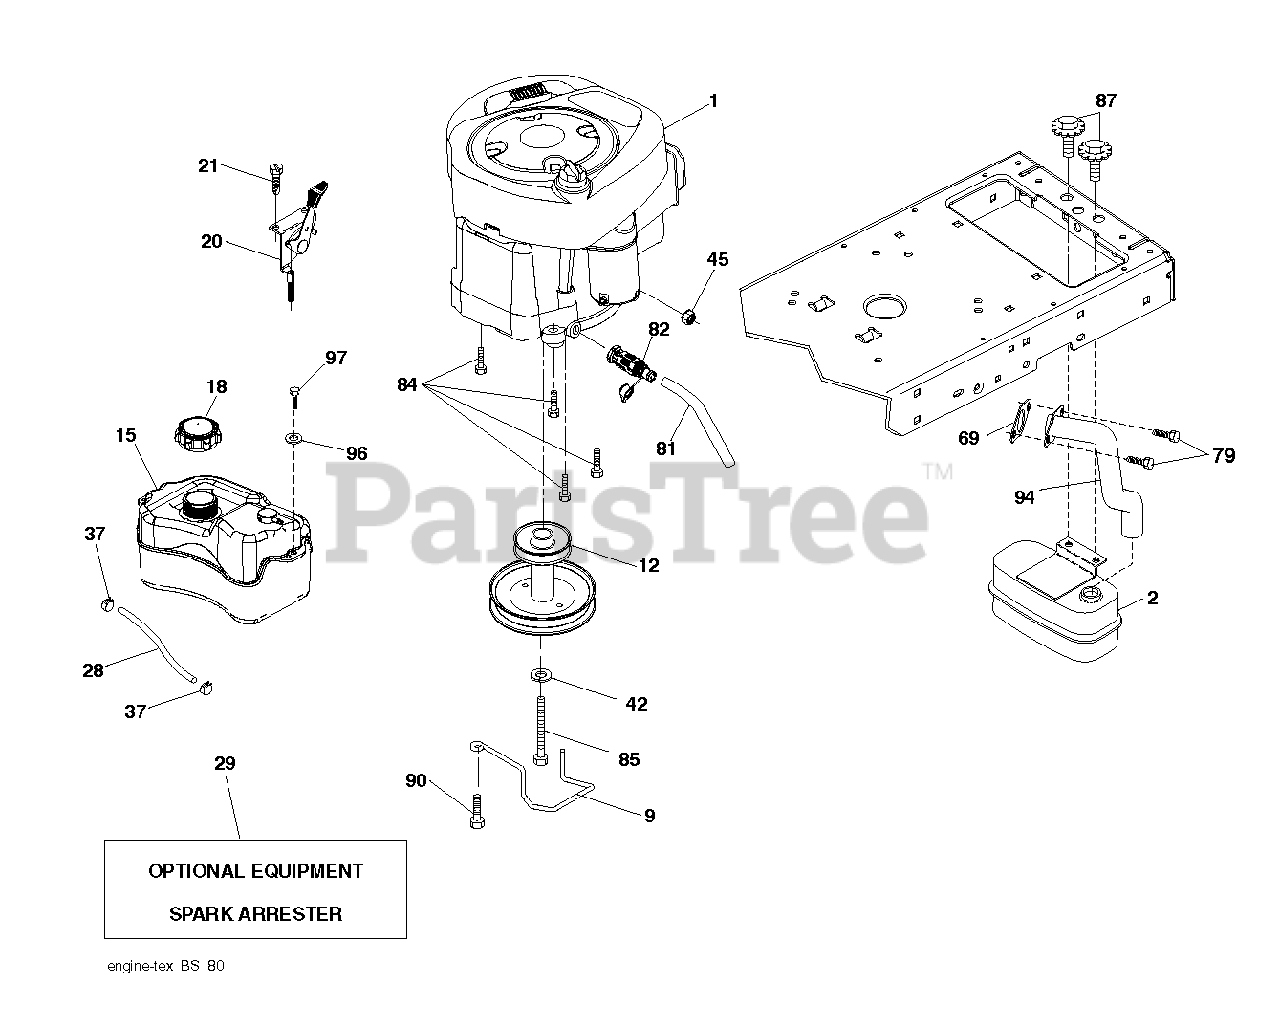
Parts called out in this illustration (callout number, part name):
2	MUFFLER.SINGLE.LRG.BRIGGS.KOHL
9	KEEPER.BELT.ENGINE.3.25
12	PULLEY ENGINE
15	FUEL.TANK.ASM.1.5.GAL.NON-EPA
18	CAP ASM.FUEL.2.25"FR.
21	SCREW.#10 X 0.750.BOS (2 2)
28	LINE.FUEL.20"FRONT.EMI
29	SPARK ARRESTOR KIT
37	HOSE CLAMP
42	LOCKWASHER
45	NUT
79	SCREW.SOCKET HD.5/16-1
81	TUBE, DRAIN OIL ASM.
82	VALUE.OIL.DRAIN
84	SCREW.3/8-16
85	BOLT HEX 7/16-20X4-1/4"
87	BOLT, 5/16-18 X 1 3/4
90	SCREW 3/8-16X1
94	RP.EXHAUST.TUBE.B&S.28/31
97	SCREW HEXWSHR 1/4-20X3/4
